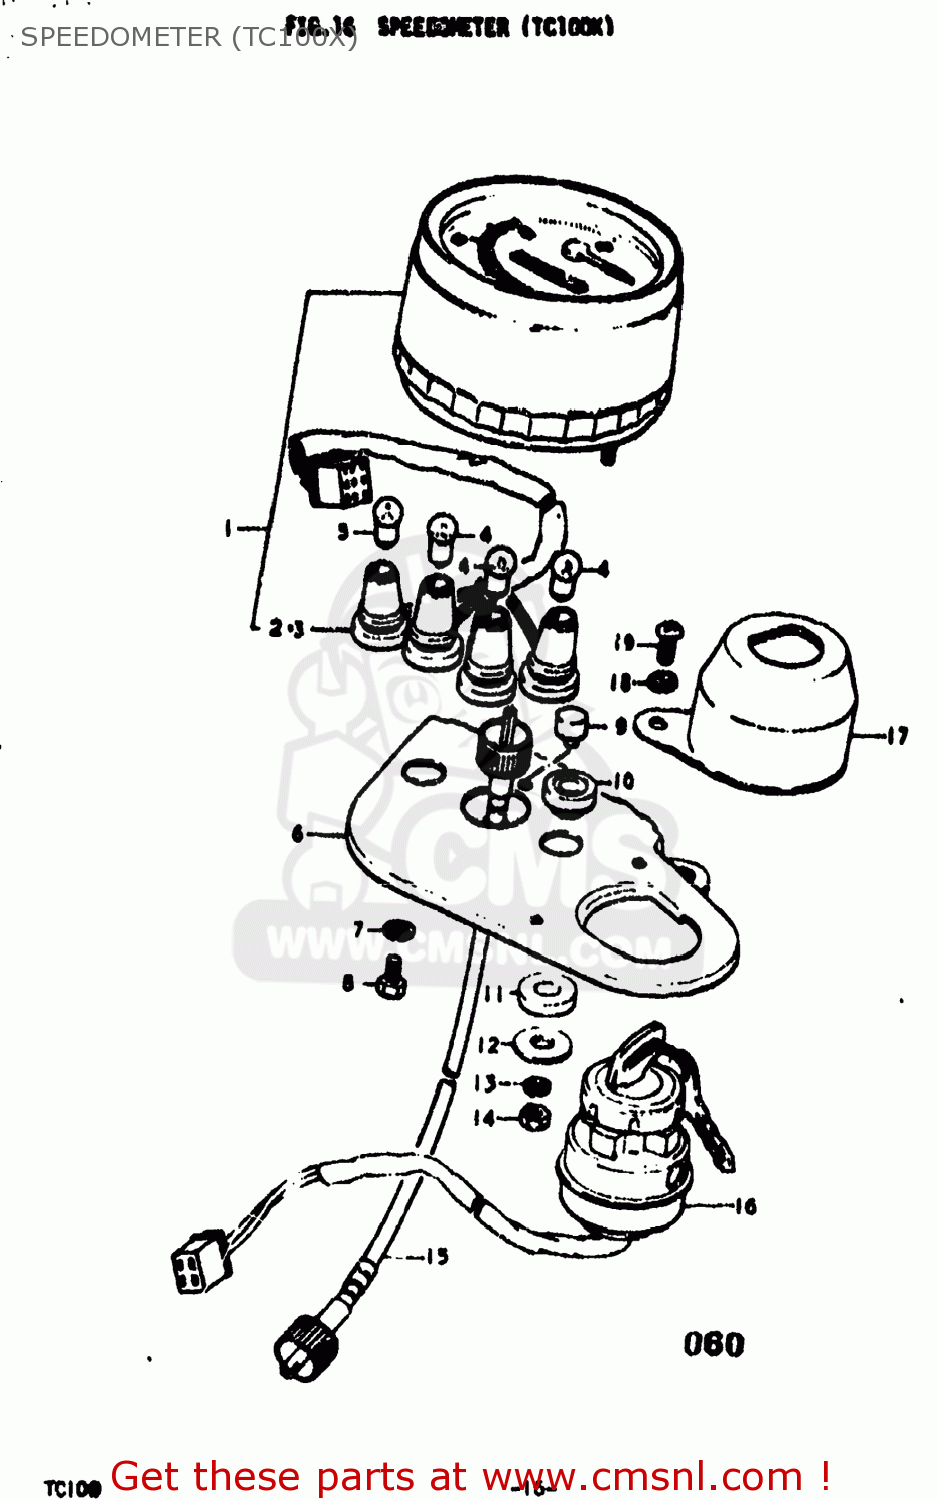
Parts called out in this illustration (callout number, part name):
1	SPEEDOMETER ASSEMBLY
2	SOCKET,METER
3	SOCKET,METER
4	BULB(6V/3W)
5	BULB(6V1.7W,STANLEY,A61A)
6	BRACKET,METER
7	LOCK WASHER
8	BOLT
9	CUSHION,METER
10	CUSHION,METER
11	CUSHION
12	WASHER(5.5X16X1.5)
13	LOCK WASHER
14	NUT
15	CABLE ASSEMBLY,SPEEDOMETER
16	SWITCH ASSEMBLY,IGNITION
17	BRACKET,IGNITION SWITCH
18	LOCK WASHER
19	SCREW
